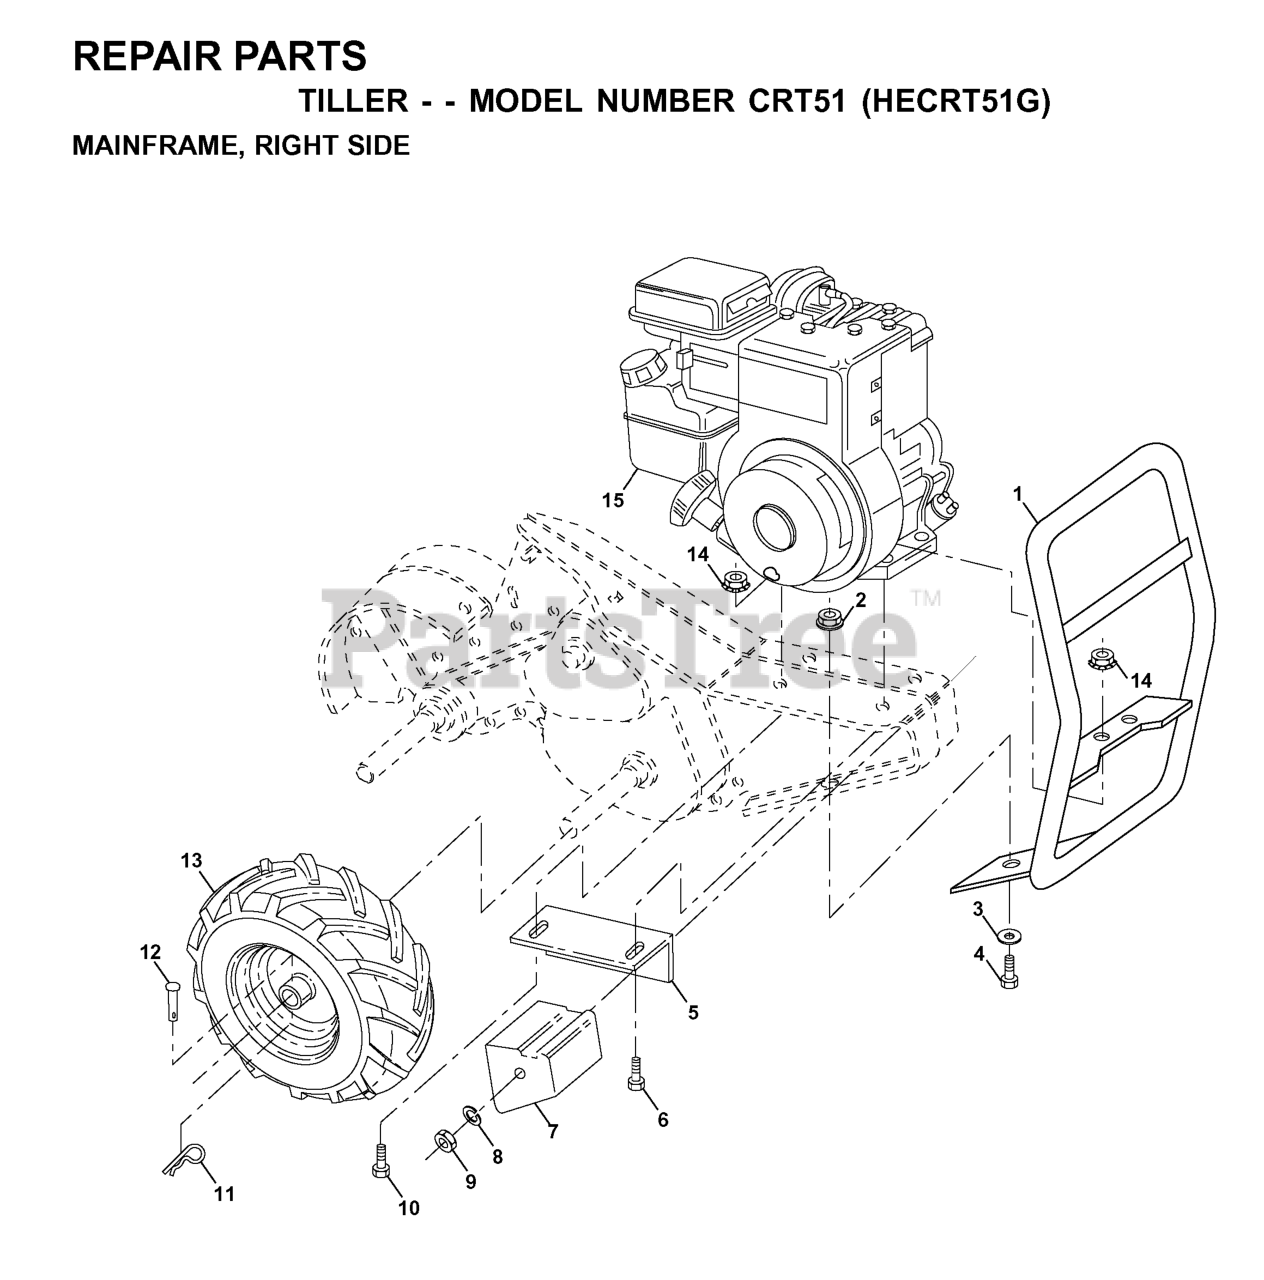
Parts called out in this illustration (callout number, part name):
1	BUMPER
2	LOCKNUT-FLANGE 5/16-18
3	WASHER
4	BOLT
5	DNO BRACKET RH CRT
6	Bolt Fin Hex 5/16 - 18 Unc x 2 Gr. 2
7	COUNTERWEIGHT, RH
8	WASHER, LOCK 3/8
9	NUT.HEX.3/8-16UNC
10	BOLT
11	RETAINER M
12	RIVET,DRILLED
13	TIRE.16X4-8.CHEVRON.TILLER
14	NUT
532124366	RIM
532124718	VALVE STEM LT
